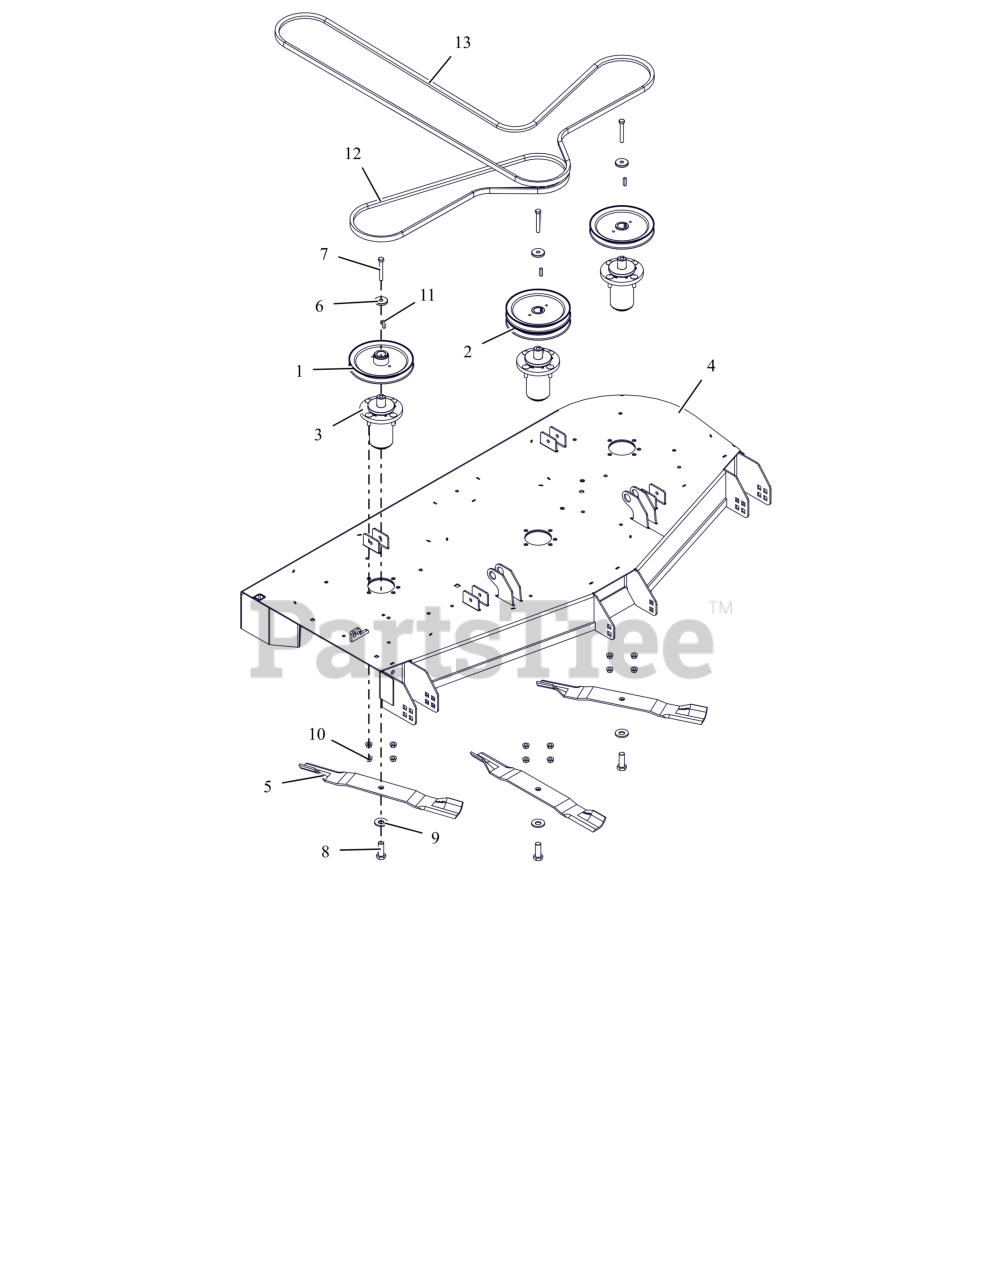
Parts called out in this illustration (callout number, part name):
1	PULLEY- V-7.50 OD X 1" ID
2	PULLEY- DOUBLE-1"X7.50"&7.50"
3	ASM, MAINT FREE ALUM SPINDLE
4	KIT,DECK-60" W/DECALS -ARIENS
5	BLADE, 20.5"
6	RETAINER, SHEAVE
7	BLT, HEX .38-16X2.75 G8 ZCC
8	BLT, HEX .62-18X1.75 G8 ZCC
9	WSHR-BLVL .669X1.535X.138
10	NUT-LK-CTR-FLG .375-16 GF ZCC
11	KEY, SQ .25X.25X1.00 RC 40-50
12	V-BELT, B-COGGED
13	V-BELT, HB SECTION
